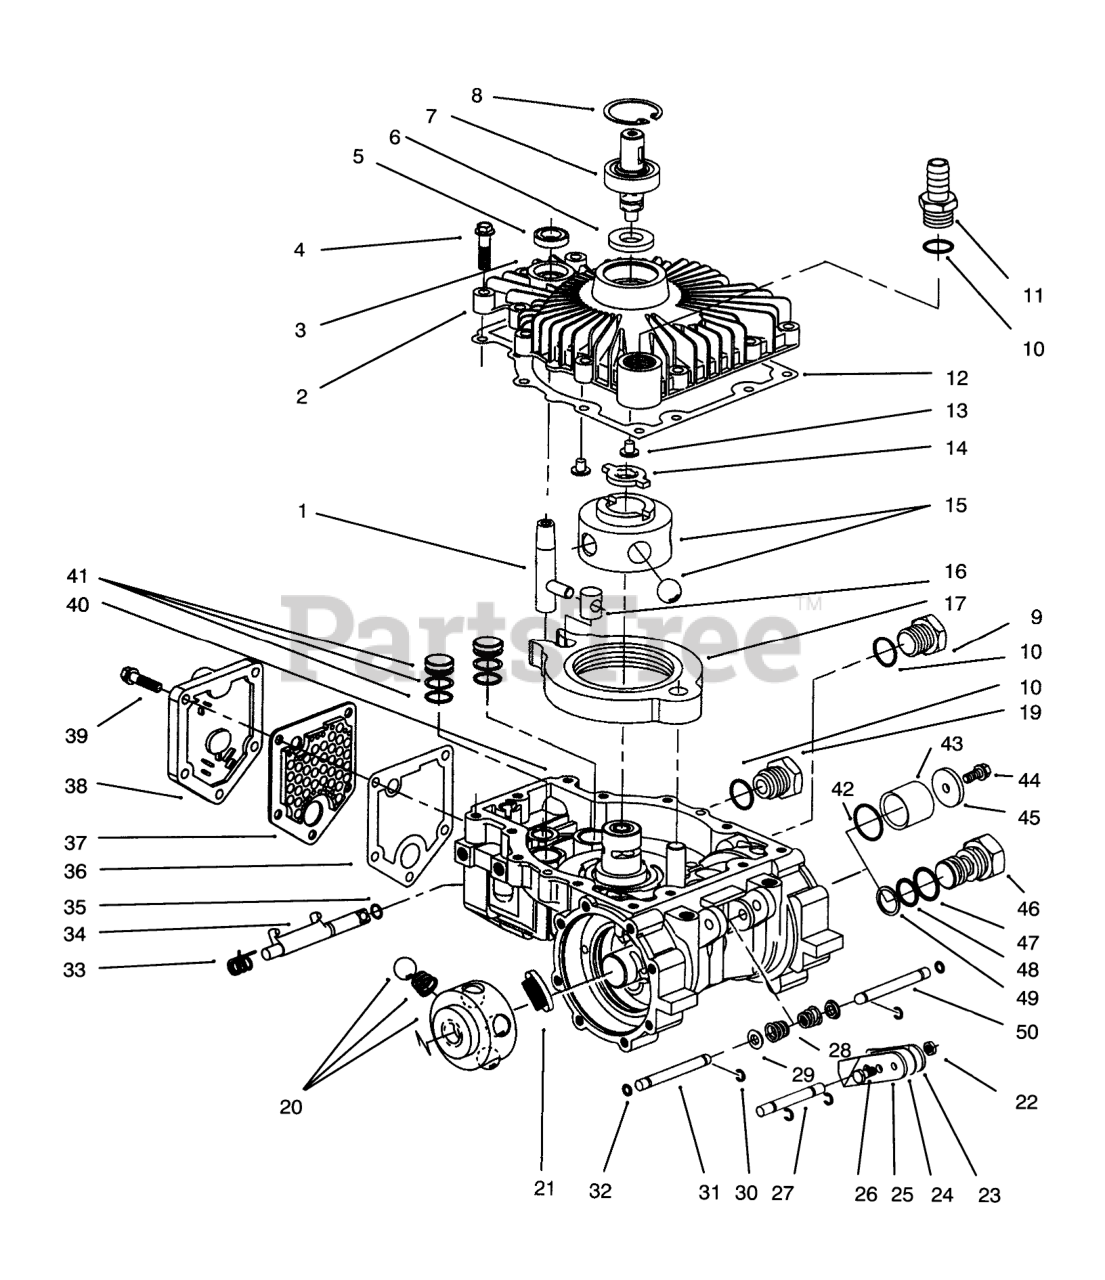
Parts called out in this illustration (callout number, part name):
1	CONTROL SHAFT
2	Cover Assembly (Incl. Ref. #3, 5-8)
3	COVER
4	1/4-20 SCREW
5	SEAL-OIL
6	Seal
7	INPUT SHAFT
8	Retaining Ring
9	Plug Assembly (Incl. Ref. #10)
10	"O" RING SEAL
11	Fitting 90deg.
12	COVER GASKET
13	Button
14	DRIVE
15	PUMP ASM
16	INSERT
17	CAM RING ASM
19	ROTOR BALL ASM
20	ROTOR BALL ASM
21	FRICTION PAD
22	LOCKNUT
23	RH BRAKE LEVER
25	LH BRAKE LEVER
26	HEX HEAD SCREW
27	BRAKE SHAFT
28	CONICAL SPRING
29	SPRING BASE
30	RETAINING RING
31	PUSH ROD
32	QUAD SEAL
33	DUMP VALVE SPRING
34	DUMP VALVE BRACKET
35	SEAL "O" RING
36	FILTER GASKET
37	FILTER
38	VALVE COVER
39	1/4-20 HEX HEAD SCREW
40	HOUSING ASM
41	PISTON ASM
42	"O" RING SEAL
43	CUP SEAL
45	WASHER
47	"O" RING SEAL
48	"O" RING SEAL
49	BACKUP RING
50	PUSH ROD
